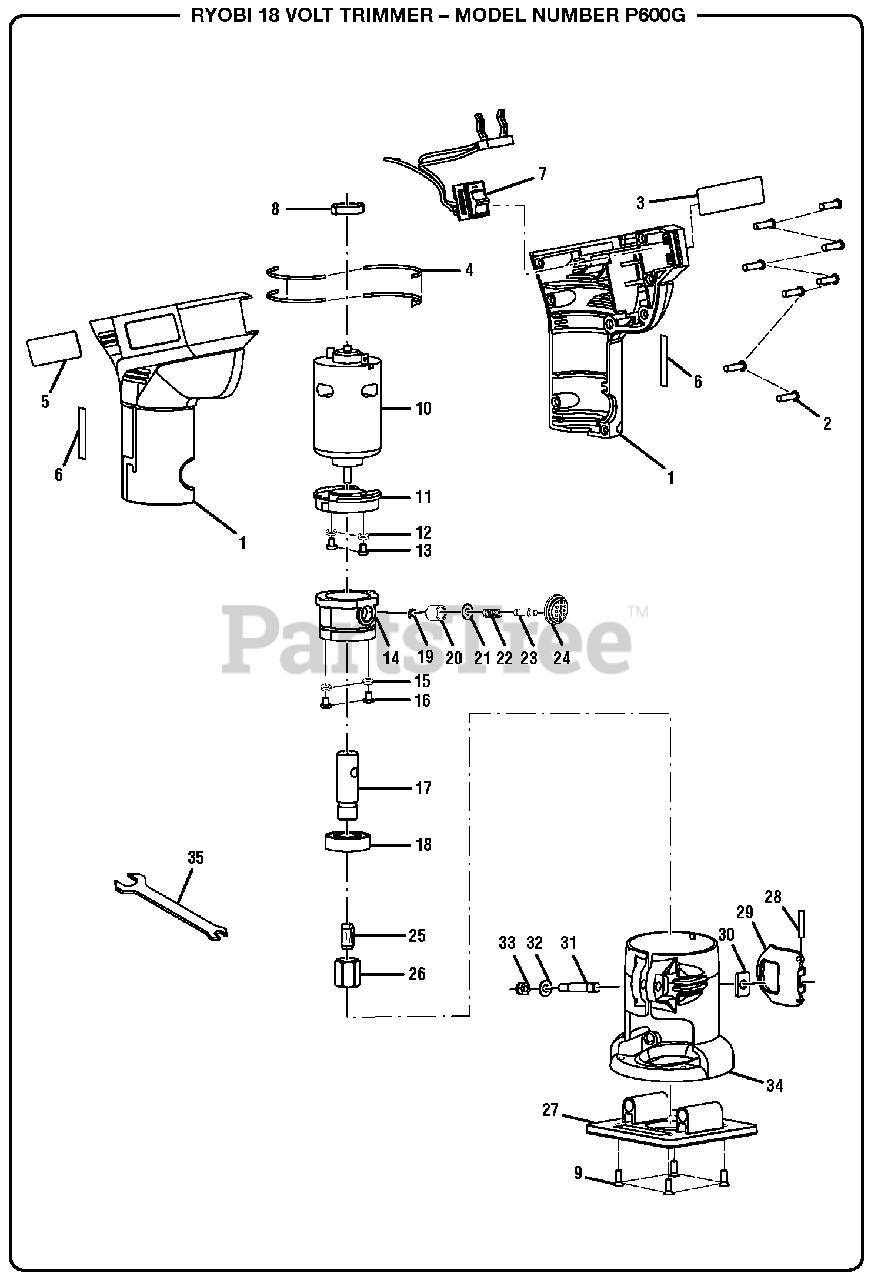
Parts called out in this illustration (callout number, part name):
1	Housing Assembly
2	Screw (M4 x 16 mm, Pan Hd.)
3	Data Label
4	Foam Rubber
5	Logo Label
6	Scale Label
7	Switch Assembly
8	Motor Back Ring
9	Screw (M4 x 12 mm, Flat Hd.)
11	Motor Base
12	Spring Washer
13	Screw (M5 x 12 mm, Pan Hd.)
14	Bearing Holder Top Cover
15	Spring Washer
16	Screw (M3 x 8 mm, Pan Hd.)
17	Output Shaft
18	Ball Bearing
19	Retaining Ring
21	Curved Washer
22	Compression Spring
23	Shaft Lock Pin
24	Lock Pin Cap
25	Collet (1/4 in.)
26	Collet Nut
27	Square Base
28	Spring Pin
29	Clamp Lever
30	Square Washer
31	Adjust Screw Shaft
34	Base Support
